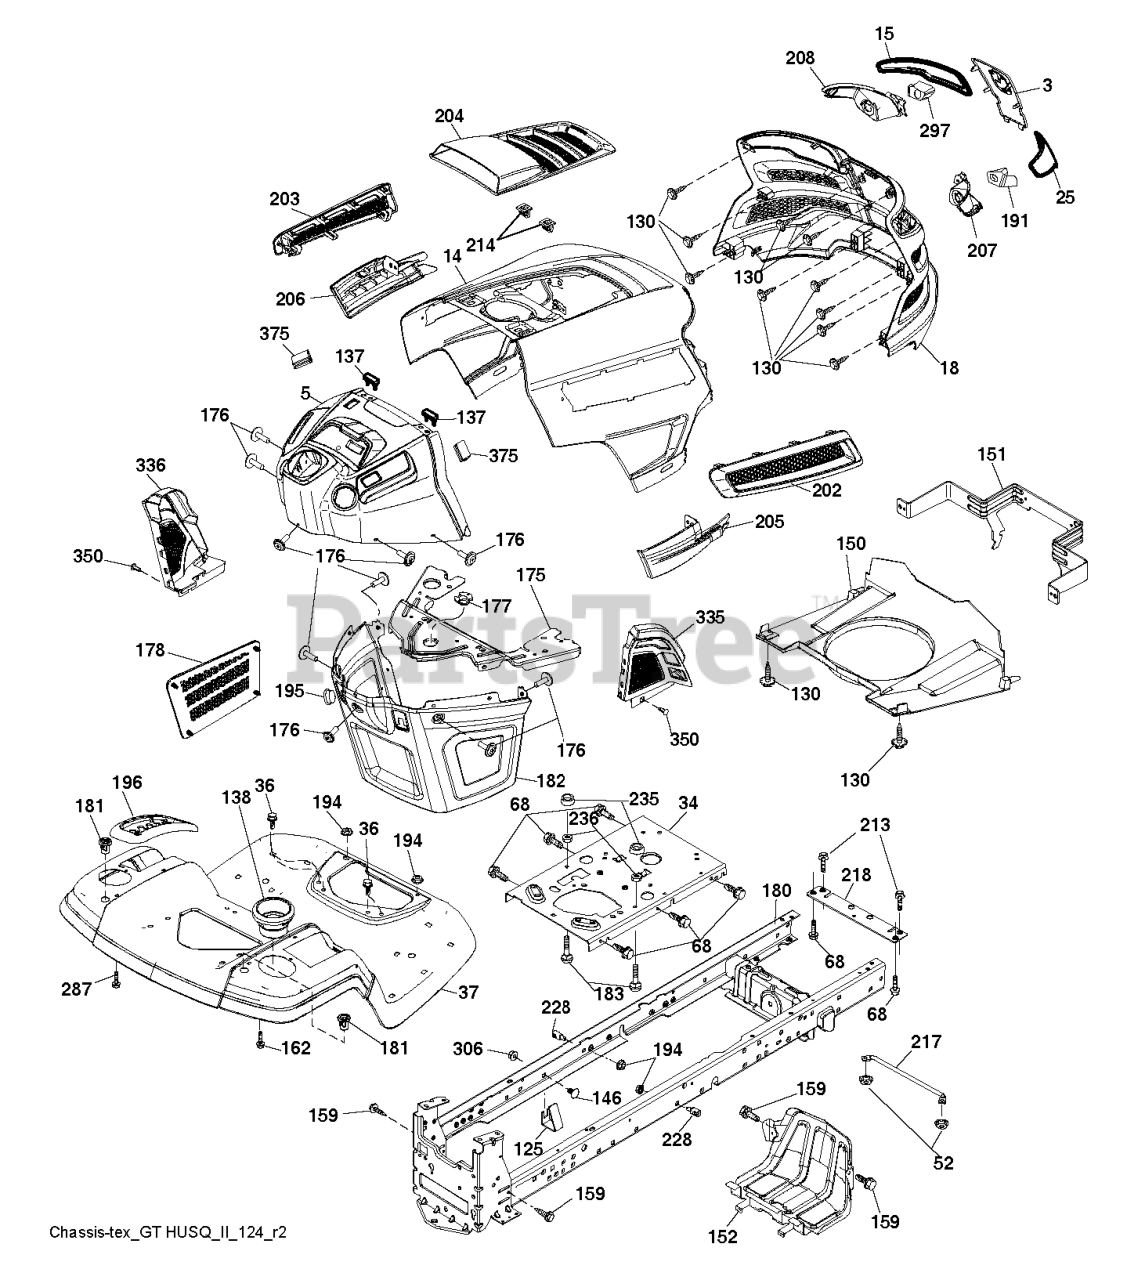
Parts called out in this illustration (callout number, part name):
3	APPLIQUE.SUBASM.GT.HUSQ.II
5	DASH.UPR.GT2.SRV.MIND.MAN.CLUT
14	HOOD.ASM.HUSQVARNA.GT.TEX.ORAN
15	LENS.HEADLIGHT.LH.GTII.2011
18	GRILLE.SUBSTRATE.2011.
25	LENS.HEADLIGHT.RH.GTII.2011
34	PLATE.ENGINE.WELDED.CHASSIS
36	SCREW 5/16"
37	FENDER.TLT.PDL.CNTRL.W/CPH.ORG
52	LOCKNUT
68	SCREW LT
125	CLIP.FUEL.LINE
130	SCREW.#10 X 0.750.BOS
137	BUMPER DASH
138	HOLDER.CUP.LT.GREY
146	BOLT.RDHD.SHT.SQNK.3/8-16X5/8
150	AIR DUCT.GTV2(1.66"RING HEIGHT
151	BRACKET.PIVOT.HOOD.GT.HUSQ.II
152	SHIELD.BROWNING.PNT.GT.V2
159	SCREW, 3/8-16X3/4
162	SCREW.HI-LO.CONSOLE
175	PLATE.CROSSMEMBER.HUSQ
176	SCREW.#10-24X5/8.RN.QU
177	BUSHING, STEERING
178	CARGO.ASM.NET.TXGT.W/C
180	CHASSIS
181	BUSHING.MNT.FEND.CRGO.TEX.49
182	DASH.LOWER.COMMON.12V.ADAPTOR
183	BOLT.5/16-18X1-1/4 FULL THD
191	INSERT.REFLECTIVE.RH.HUSQ.GTII
194	NUT LOCK HEX FLANGE 5/16-18
195	PLUG.HOLE.DASH.LOWER.12V.BLK
196	DECKLFT.CONSOL FULL ASSM GREY
202	VENT.SIDE.RH.GT.HUSQ.II.
203	VENT.SIDE.LH.GT.HUSQ.II.498
204	VENT.TOP.ASM.HUSQ.GT2
205	SIDE.TRIM.RH.GT.HUSQ.II
206	SIDE.TRIM.LH.GT.HUSQ.II.GRAY
207	BEZEL LIGHT.RH.GT.II.MYLAR
208	BEZEL LIGHT.LH.GT.II.MYLAR
213	BOLT
214	CLIP.RETAINER.TINNER.
217	ROD.PIVOT.HOOD
218	X-PIECE.HOOD.STOP.NON/
228	STUD.FASTNER.W/ANTI-ROTATE
234	BUMPER.HOOD.TEX.HUSQVARNA
235	SPACER FENDER
236	NUT.CENTERLOCK.5/16-
287	SCREW 1/4X20
297	INSERT.REFLECTIVE.LH.HUSQ.GTII
306	NUT LOCK FLG 3/8-16 UNC
335	COVER.LOWER.DASH.RH.BLACK
336	COVER-LH.LOWER.DASH.GT2.BLACK
350	CLIP.X-MAS.TREE
